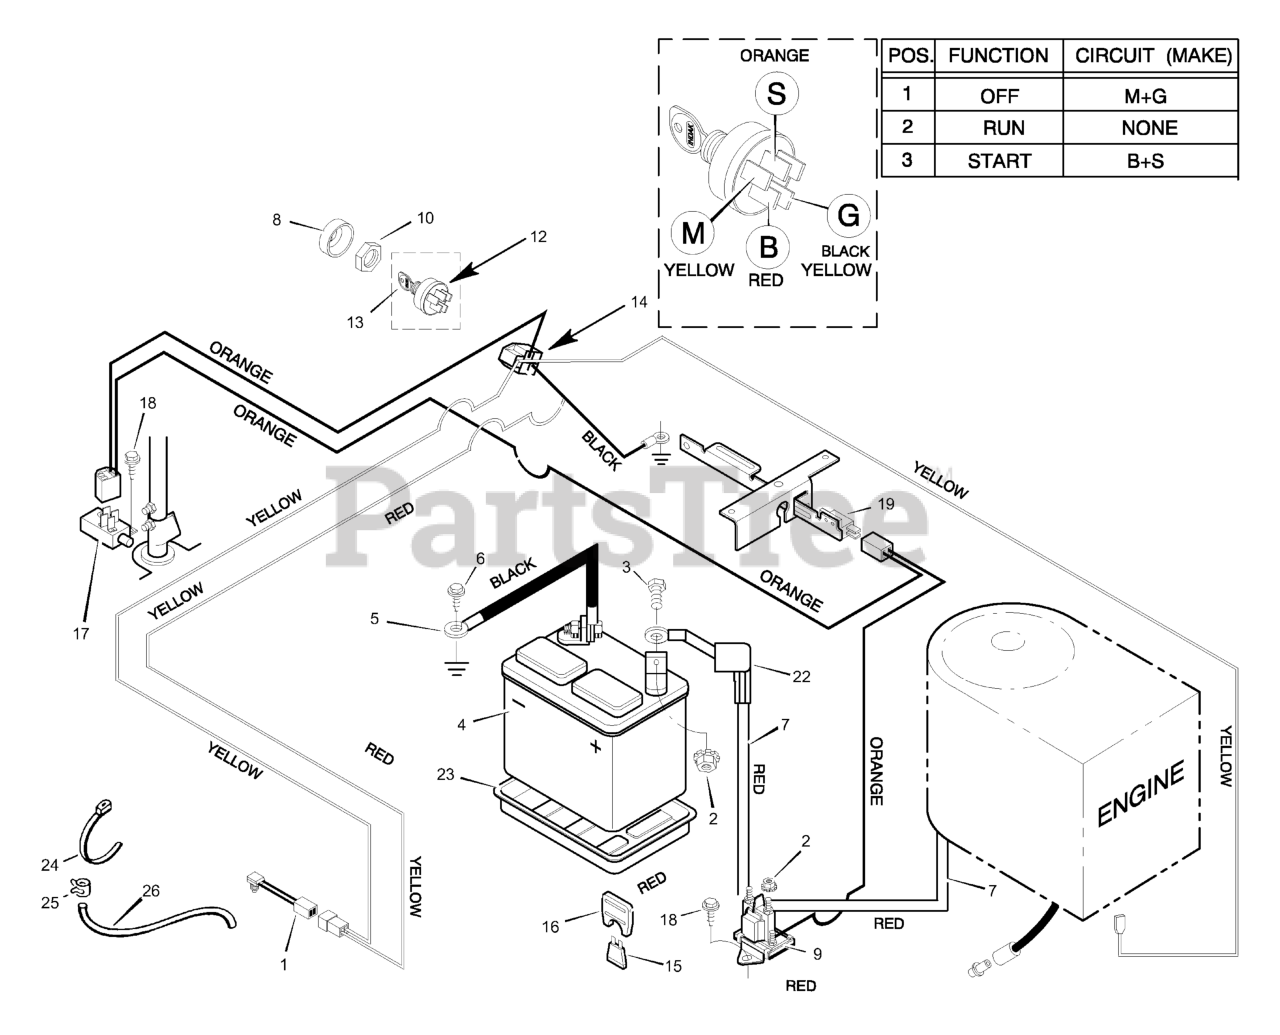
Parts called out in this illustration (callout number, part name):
1	Switch, Seat Sensor
2	Locknut
3	BOLT, Hex
4	Battery
5	CABLE, Battery Ground (Black)
7	CABLE, Positive Battery (Red)
8	Cap, Ignition Switch
9	Solenoid
10	NUT, Ignition Switch
12	Switch, Ignition
13	Key, Ignition
14	Harness, Wire
16	Holder, Fuse
17	Switch, Attachment Clutch
19	Switch, Limit
22	Cover, Terminal
23	Tray, Battery
24	Strap, Tie
26	Tube, Battery Drain
